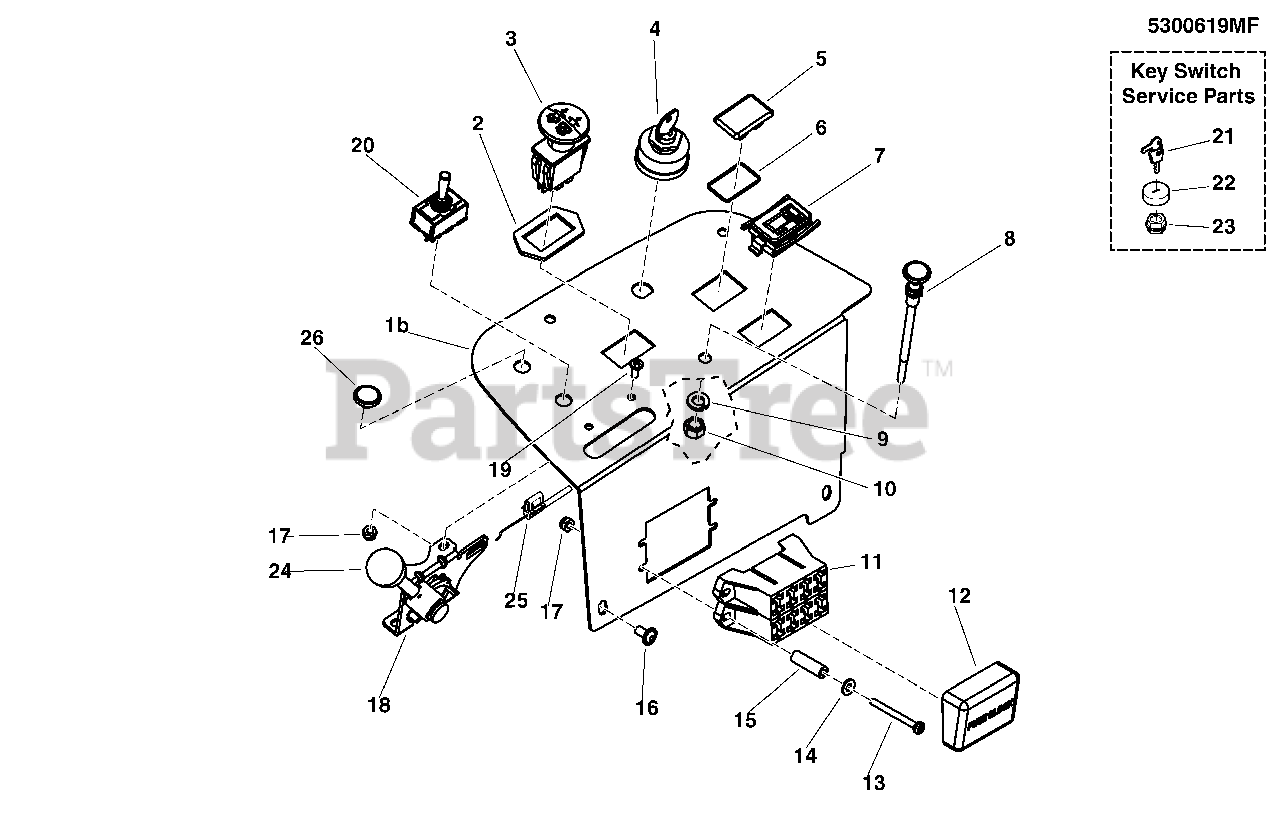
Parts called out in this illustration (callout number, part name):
1	DASH PANEL - BLACK
2	RING, SWITCH RETAINER, PTO
3	SWITCH, Blade Engage
4	SWITCH, IGNITION, 25 AMP, 6 PO
5	PLUG, Hole, Electric Lift (Hydro models only)
6	O-RING, 7/8" ID X 1/16" W
7	HOUR METER, ASSEMBLE
8	CABLE, CHOKE CONTROL, 39.5"
9	WASHER, 3/8" SPLIT LOCK
10	NUT, 3/8 - 24 HEX
11	FUSE, BLOCK
12	COVER, DOUBLE FUSE BLOCK
13	SCREW, #10-24 X 2 ROUND PHILLIPS
14	WASHER, #10 SAE
15	SPACER, .20 X .38 X 1.25
16	SCREW, ALLEN HEAD 1/4-20 X .500 ZINC PHOS
17	NUT, Nylock, #10-24, GR2
18	LEVER, THROTTLE CONTROL, HEAVY DUTY
19	SCREW, #10-24 X 1/2" ROUND PHILLIPS
20	SWITCH, Actuator
21	KEY, IGNITION MOLDED SET (SV)
22	COVER, PLASTIC, SNAP ON (SV)
23	NUT, PLASTIC (SV)
24	THROTTLE CONTROL HANDLE/KNOB
25	CABLE, THROTTLE, 42"
26	PLUG, 1/2, BPF - 1/2
